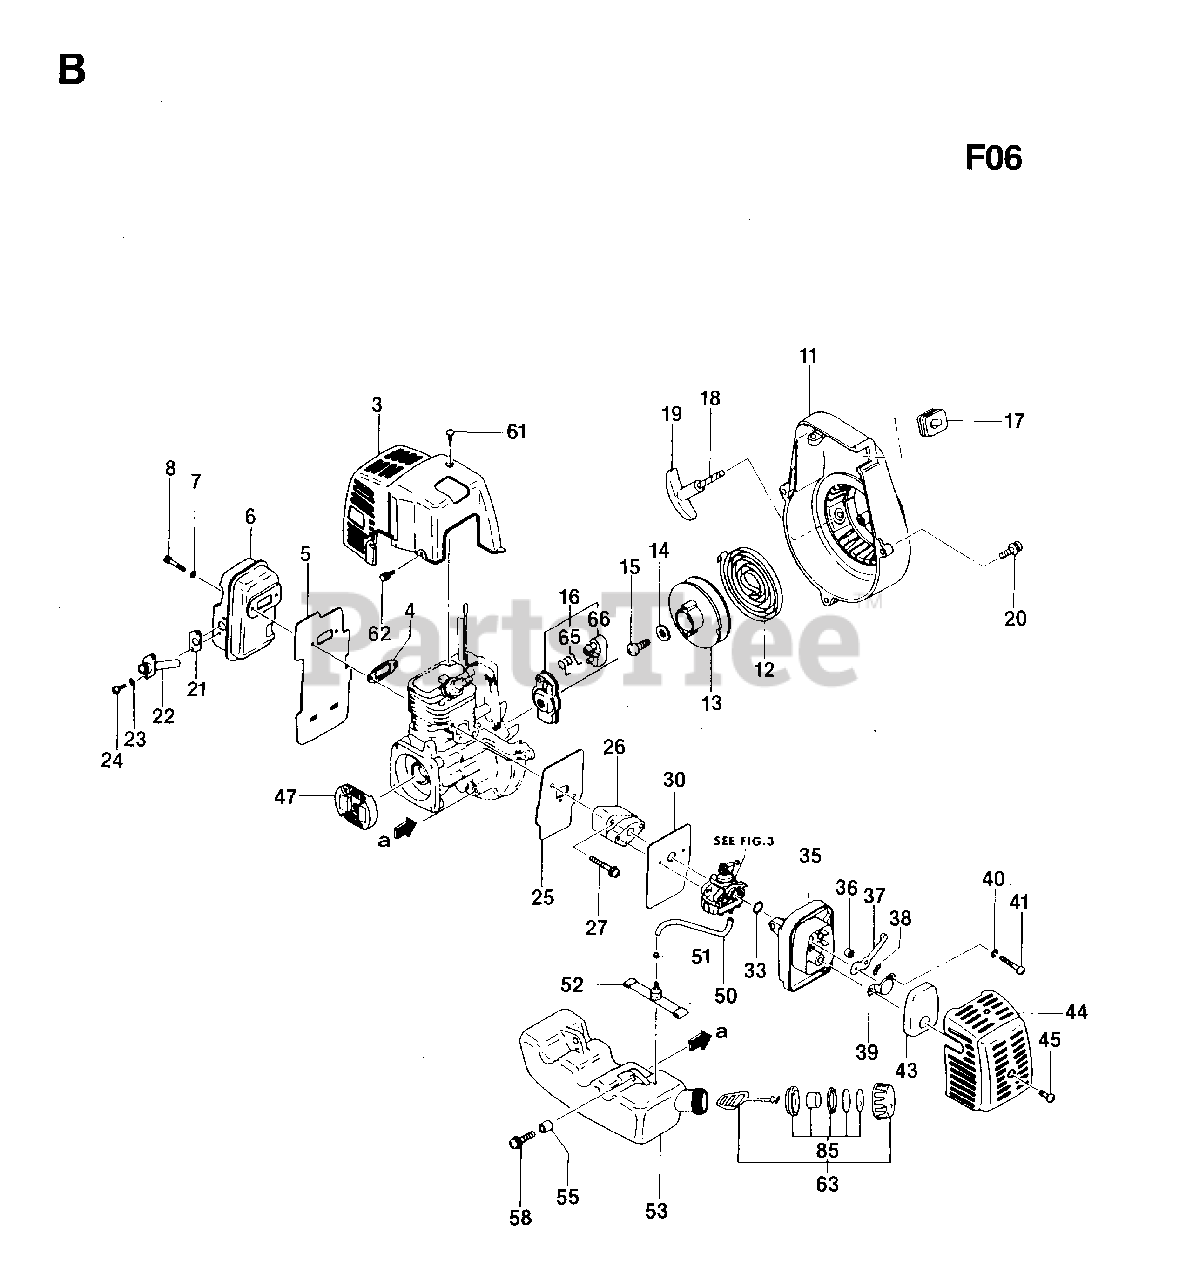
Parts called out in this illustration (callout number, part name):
7	WASHER 5.3X12
8	SCREW MC6S 5X50
23	SPRING WASHER 4.1X7.1
24	SCREW MC6S 4X8
40	SPRING WASHER
41	SCREW MC6S 5X60
